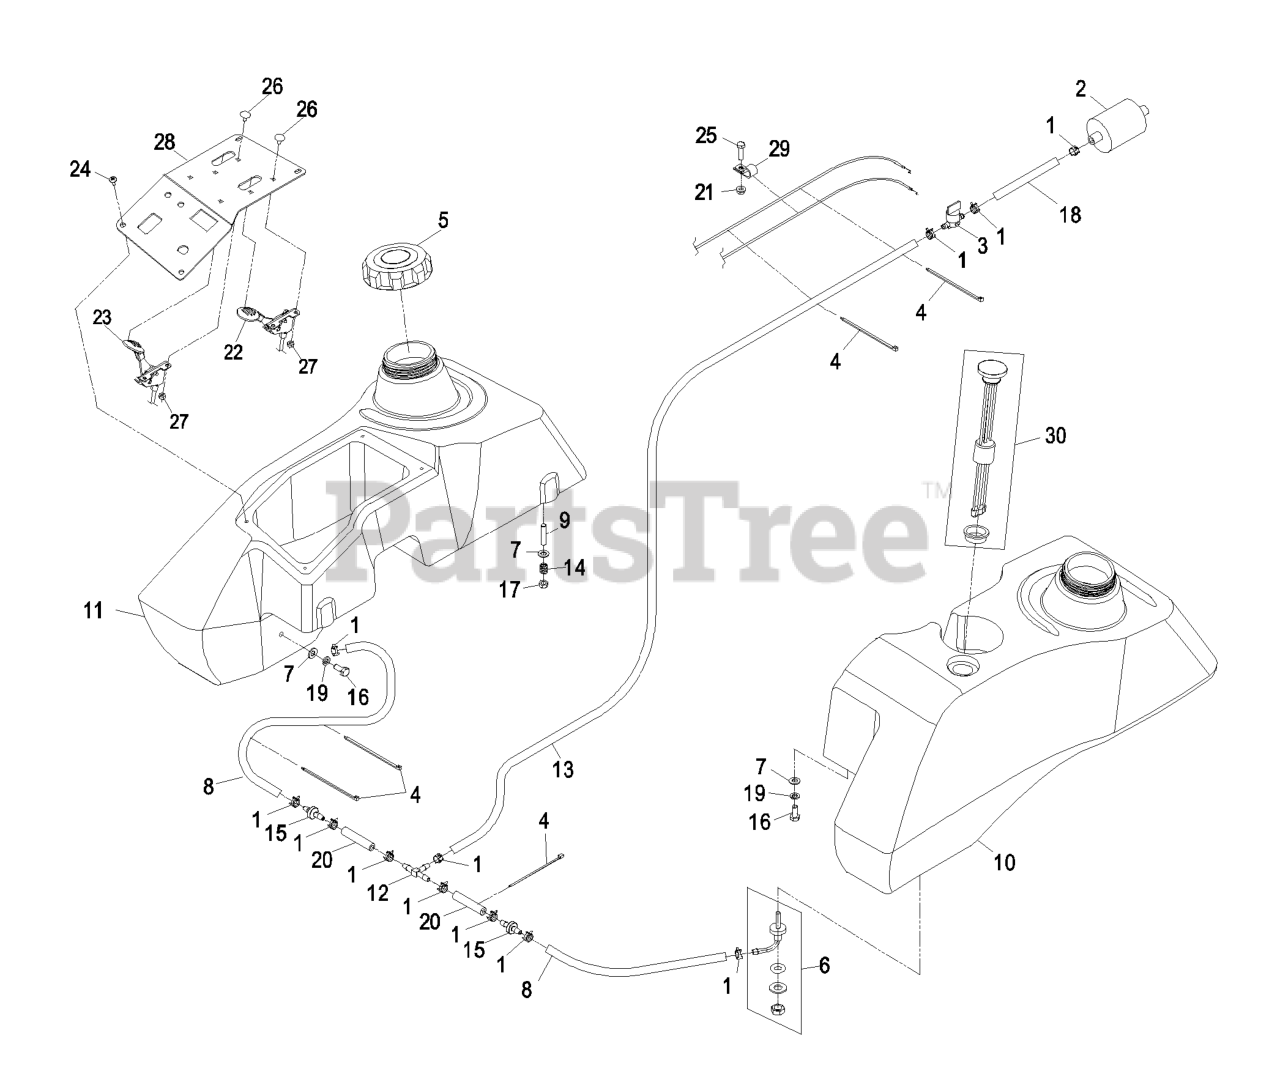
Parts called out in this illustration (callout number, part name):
2	Kohler Part No 2405010 Fuel Filter
3	VALVE-FUEL
4	TIE-PLASTIC
5	CAP-FUEL, GAS
6	FITTING-FUEL, BULKHEAD
7	WASHER-PLAIN
8	HOSE-FUEL
9	STUD
10	ASM,FUEL TANK LH
12	FITTING-TEE, BARBED
13	HOSE-FUEL
14	SPRING-TANK, FUEL
15	VALVE-CHECK, FUEL
16	SCREW-HH
17	NUT-LOCK, NI
18	HOSE-FUEL
19	WASHER-LOCK
20	HOSE-FUEL
22	CONTROL-THROTTLE
23	CONTROL,CHOKE
24	SCREW-PPH
25	SCREW-HH
26	BOLT-CARR
27	NUT-LOCK, NI
28	PANEL,CONTROL W/DECALS
29	CLIP-LOOM
30	Kit, Gauge Fuel
